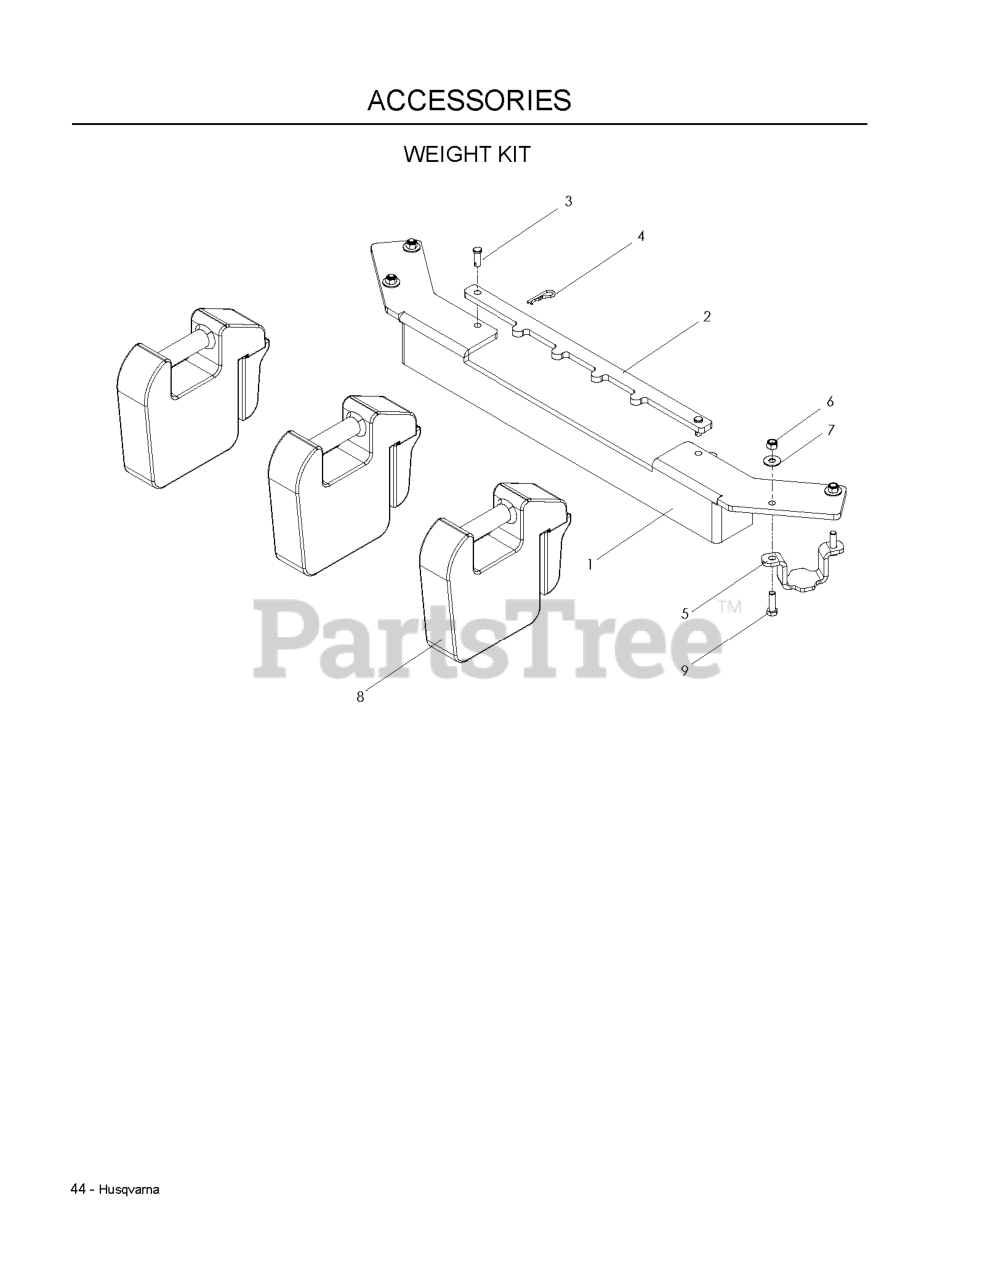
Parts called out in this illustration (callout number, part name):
1	FRONT WT BAR, BLACK
2	HOLD DOWN, WEIGHT BAR
3	CLEVIS PIN
4	RETAINER SPRING
5	WEIGHT KEEPER
6	NUT 3/8-16 NYLOC
7	WASHER 3/8 FLAT
8	FRONT WEIGHT CAST PZ DFS
9	HCS 3/8C X 1 1/4 GR5
